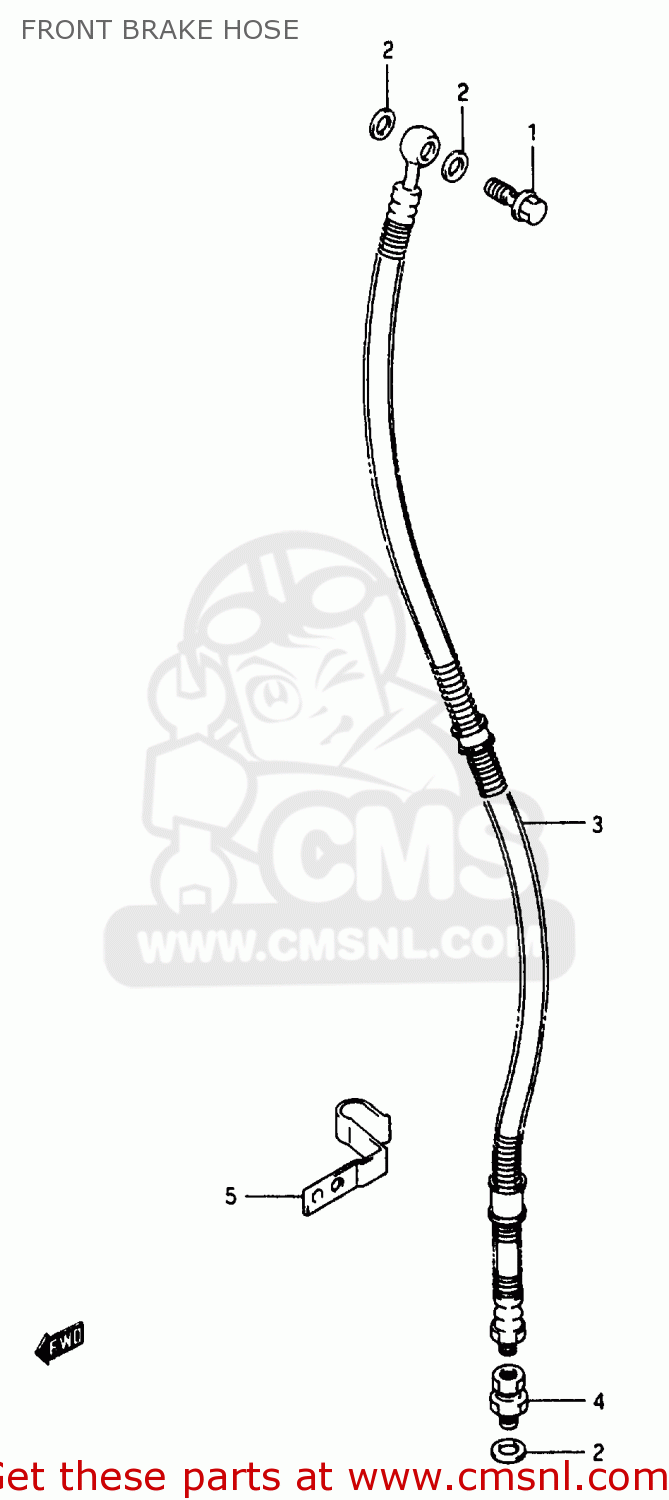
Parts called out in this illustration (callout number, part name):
1	BOLT UNION
2	WASHER(10X15X1.5)
3	HOSE,FR BRAKE
4	ADAPTER,BRAKE HOSE
5	GUIDE,BRAKE HOSE
